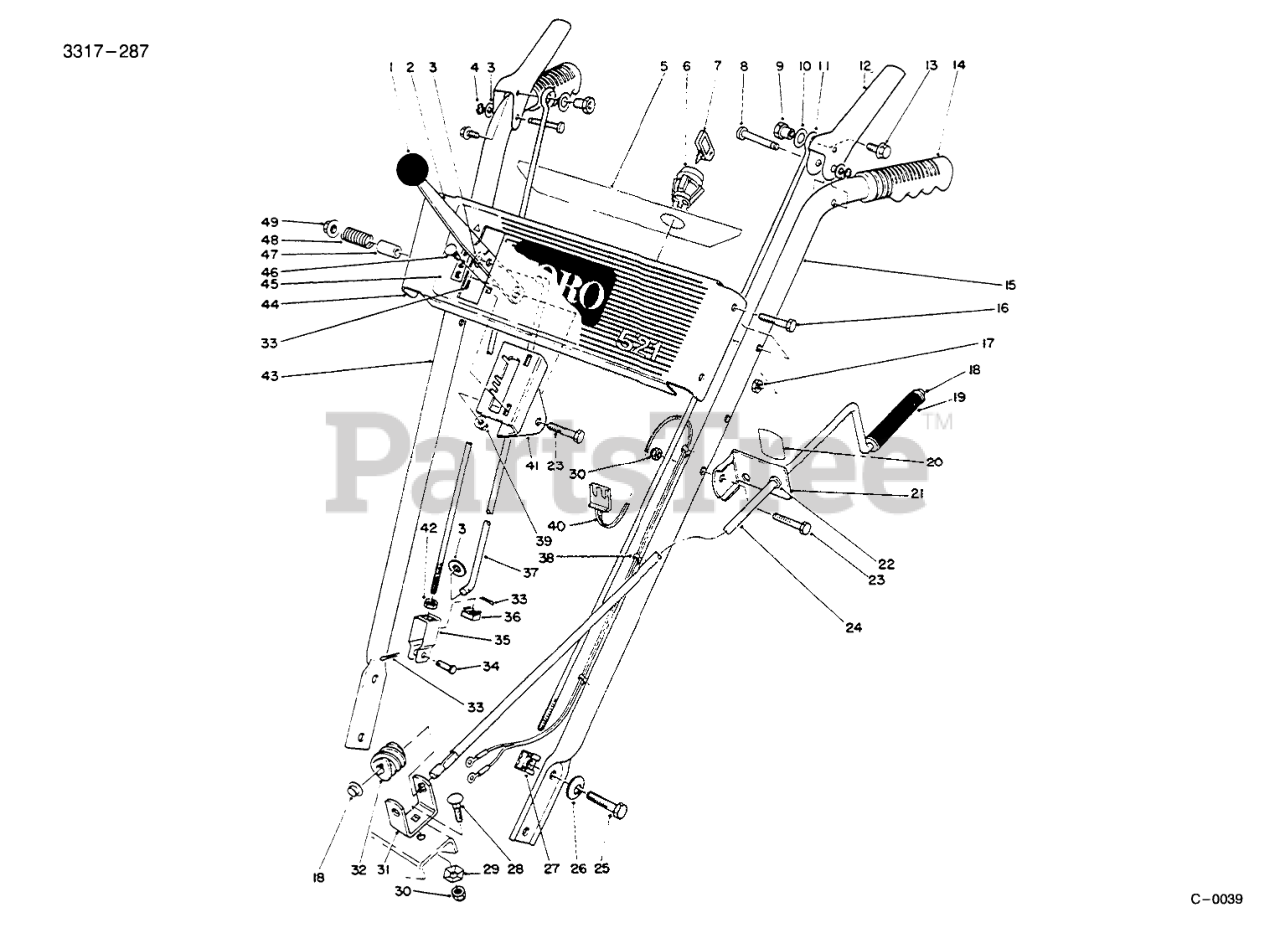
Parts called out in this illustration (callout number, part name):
2	SPEED SELECTOR B
3	WASHER-PLAIN
4	RING-CLIP
5	DECAL - ESCUTCHEON BACK
6	SWITCH
7	KEY-IGNITION
8	PIN-LEVER, CONTROL
9	POST-MOUNTING, LINKAGE
10	WASHER-FLAT
11	LINK-UPPER
12	HANDLE-CONTROL
13	SCREW-HHF
14	GRIP-HANDLE
15	Handle-Left
16	SCREW-HH
17	NUT-LOCK, NI
18	RETAINER-PUSH ON
19	GRIP-CONTROL, CHUTE
20	DECAL-CHUTE DIRECTION
21	Bracket-Chute Control (Incl. Ref.# 20 & 22)
22	Bushing
23	SCREW-HH
24	ROD-CONTROL, CHUTE
25	SCREW-HH
26	WASHER-BELLEVILLE
28	SCREW-CARR
29	WASHER-LOCK
30	NUT-LOCK, NI
31	BRACKET-WORM
32	GEAR-WORM, CHUTE
33	PIN-COTTER
34	PIN-CLEVIS
35	CLEVIS
36	NUT-RETAINED
37	ROD-SELECTOR, SPEED
38	Mount-Wire
39	NUT-HF
40	Wire Harness Assembly (Incl. Ref.# 38)
41	Mount-Speed Selector
42	NUT-JAM
43	Handle-Right
44	ESCUTCHEON PLT B
45	DECAL ESCUTCHEON
46	SCREW-CARR
47	SPACER
48	SPRING
49	NUT-HF
